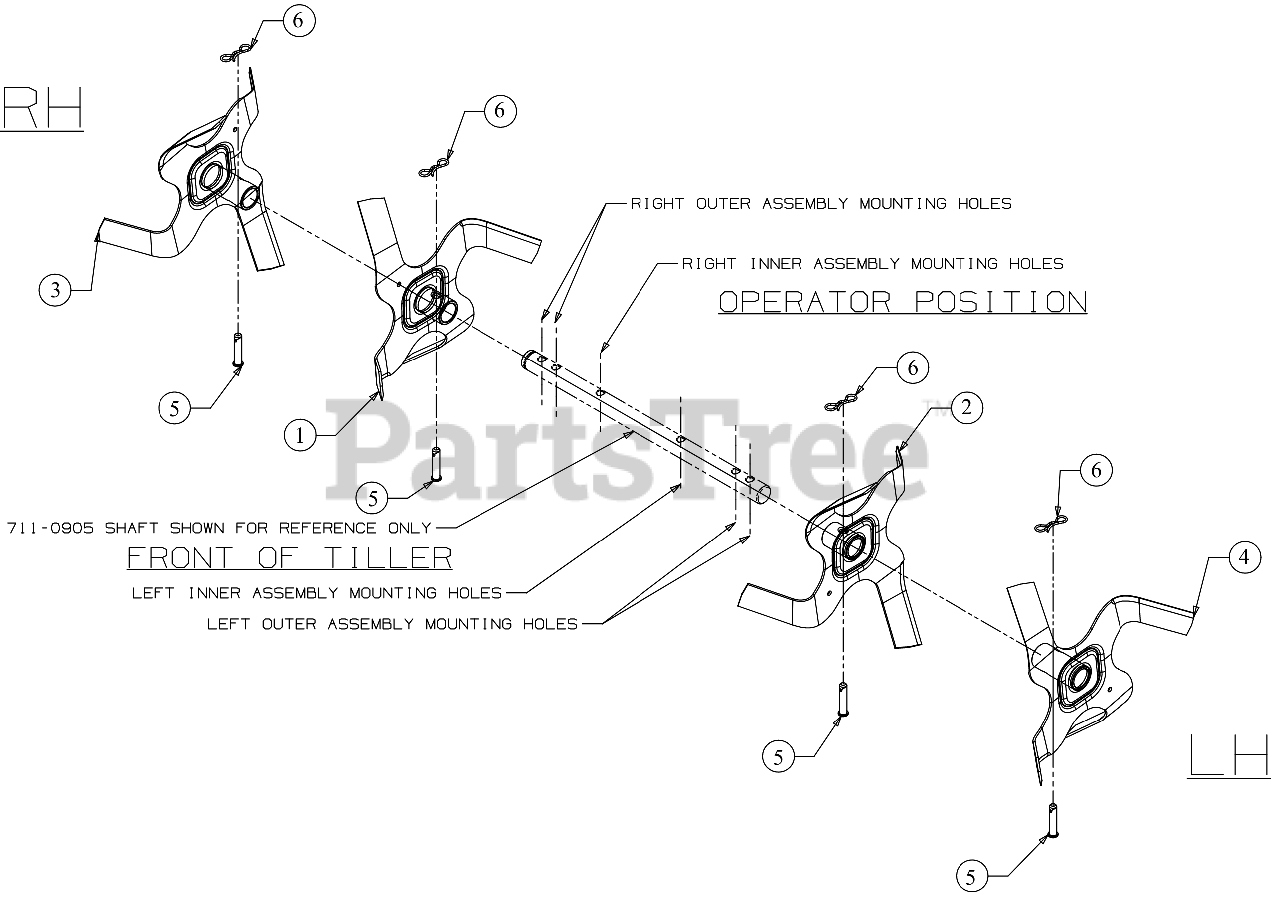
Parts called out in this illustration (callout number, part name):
1	TINE ASSEMBLY (INNER) (RH)
2	TINE ASSEMBLY (INNER) (LH)
3	TINE ASSEMBLY (OUTER) (RH)
4	TINE ASSEMBLY (OUTER) (LH)
5	CLEVIS PIN .375 X .1.75
6	PIN:COTTER
